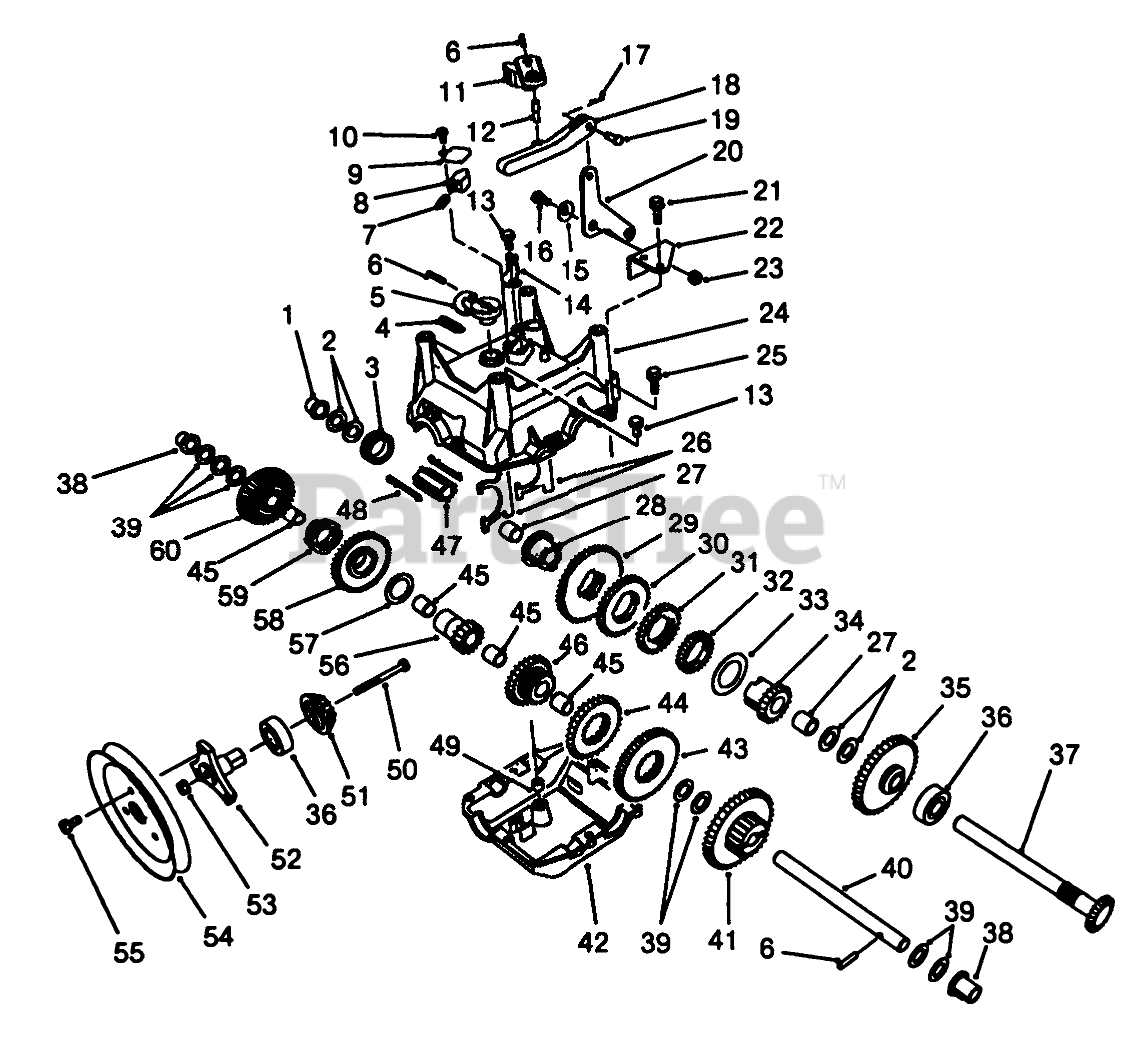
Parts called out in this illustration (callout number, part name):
1	BUSHING-FLANGE, OUTPUT
2	BEARING-THRUST
3	COLLAR-SHIFT
4	SPRING-EXTENSION
5	Lever-Direction Shift
6	PIN-SPRING
7	SPRING-DETENT
8	BUTTON-DETENT
9	COVER-DETENT
10	SCREW-HWH
11	LEVER-SHIFT, GEAR
12	PIN-LINK, GEAR SHIFT
13	SCREW-HWH
14	BRACKET-CABLE
15	WASHER-CURVED
16	SCREW-SHOULDER
17	PIN-COTTER
18	LINK-SHIFT, GEAR
19	PIN-CLEVIS
20	BELLCRANK
21	SCREW-HWH
22	BRACKET-BELLCRANK
23	NUT-LOCK, NI
24	GEARCASE-UPPER, CASING
26	YOKE-SHIFT
27	BUSHING-OUTPUT
28	SLEEVE-GEAR
29	GEAR-45 T
30	GEAR-34 T
31	GEAR-27 T
32	GEAR-29 T
33	WASHER-THRUST
34	GEAR-SLEEVE, 19 T
35	GEAR-41 T
36	BEARING-BALL
37	SHAFT-OUTPUT
38	BUSHING-INTERMEDIATE
39	WASHER-THRUST
40	SHAFT-INTERMEDIATE
41	GEAR-19/41 T
42	GEARCASE-LOWER, CASING
43	GEAR-51 T
44	GEAR-33 T
45	Bushing-Output
46	Gear-26T
47	Sleeve-Shift
48	KEY-SHIFT
49	BUSHING-YOKE
50	SCREW-HH
51	PINION-BEVEL
52	HUB-PULLEY
53	NUT-HHF
54	TRACTION-SHEAVE, HALF
55	SCREW
56	GEAR-BEVEL, 15 T
57	WASHER-THRUST
58	Gear-Bevel 36T
59	Collar-Shift
60	Gear-Bevel Reverse 36T
